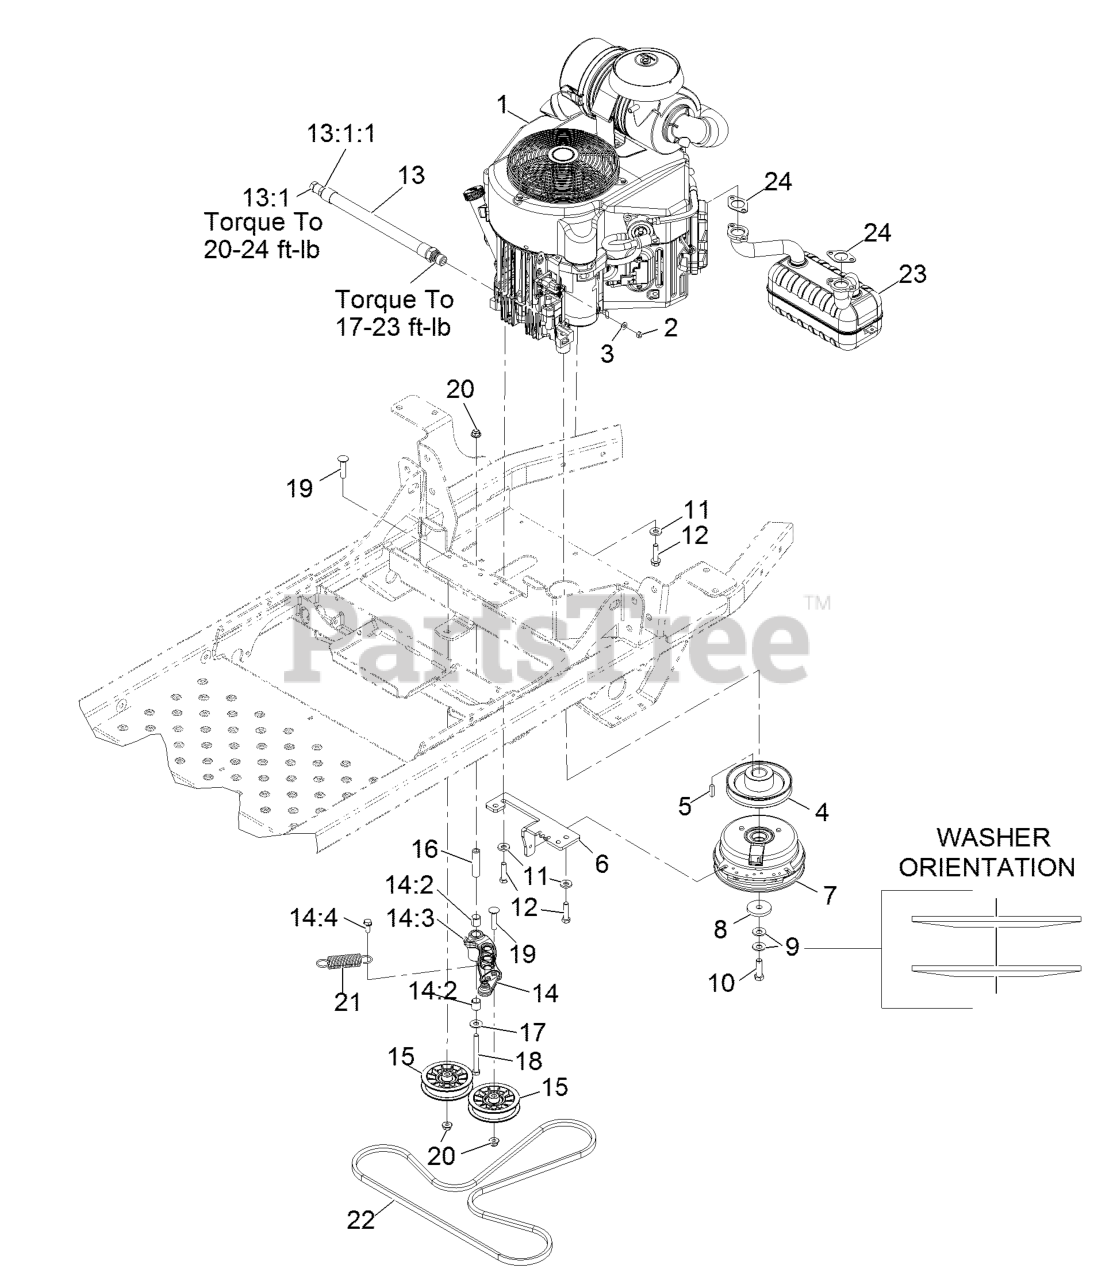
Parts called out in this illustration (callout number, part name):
2	NUT-HEX
3	WASHER-FLAT
4	SHEAVE-PUMP, DRIVE
6	ANCHOR-CLUTCH
8	WASHER-CLUTCH
9	WASHER-SPRING
10	SCREW-HH 7/16-20 X 1 1/2 W/LOCTITE
11	WASHER-BELLEVILLE
12	SCREW-HH
13	ENGINE OIL DRAIN HOSE ASM
13:1	PLUG-HH
13:1:1	O-RING
14	IDLER ARM ASM
14:2	SLEEVE-BEARING
14:3	FITTING-GREASE, 90 DEG
14:4	SCREW-THD ROLL, HWH
15	PULLEY-FLAT IDLER
16	BUSHING-PIVOT, IDLER
17	WASHER-FLAT
18	SCREW-CARR
19	SCREW-CARR
20	NUT-HF, NI
21	SPRING-EXTENSION
22	V-BELT
23	MUFFLER-KAWASAKI
24	GASKET-EXHAUST
